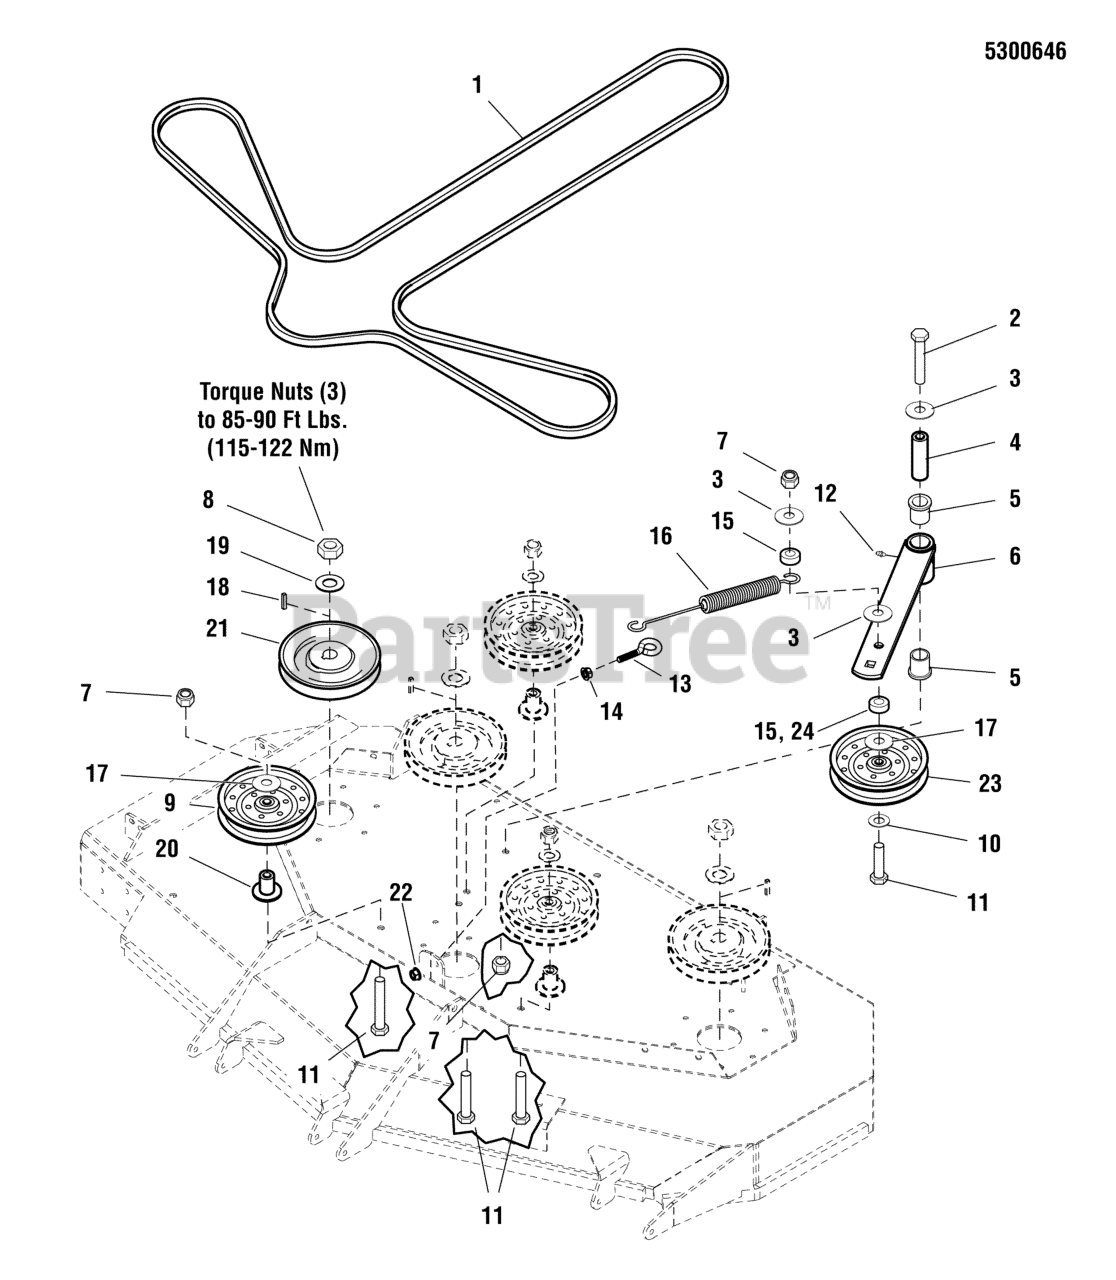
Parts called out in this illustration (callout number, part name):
1	BELT, 5V, 175.90EL, LG ARAMID, WRPD, RC
2	BOLT, 1/2-13 X 4-1/2" GD5
3	WASHER, 1/2" USSZ
4	SPACER, .52 X 1.00 X 3.50
5	BUSHING, FLANGE
6	IDLER ARM ASSM
6	ASSM, IDLER ARM
7	NUT, Hex Flange, Nylock, 1/2-13
8	NUT, 3/4-16 HEX
10	WASHER, 1/2" GD9 YZ
11	BOLT, 1/2-13 X 3" GD5 CZ
12	GREASE FITTING, 1/4-28 STRAIGHT
13	EYE BOLT, 3/8-16 X 6, 3.0 THREAD
13	EYE BOLT, 3/8-16 X 2.96, 1.25THRD, .7EYE
14	NUT, 3/8-16 HEX JAM
15	SPACER, .52 X 1.00 X .38
16	SPRING, EXTENSION, SWIVEL END
17	SHIELD, PULLEY BEARING
18	KEY, 1/4" SQ. X 1-1/4
19	WASHER, 3/4 BELLEVILLE
20	IDLER MOUNT
21	PULLEY, 6.93 EOD X 25MM, SPLIT
22	NUT, 3/8-16 HEX NYLOCK FLANGE
24	SPACER, .52 X 1.00 X .56, CZ
